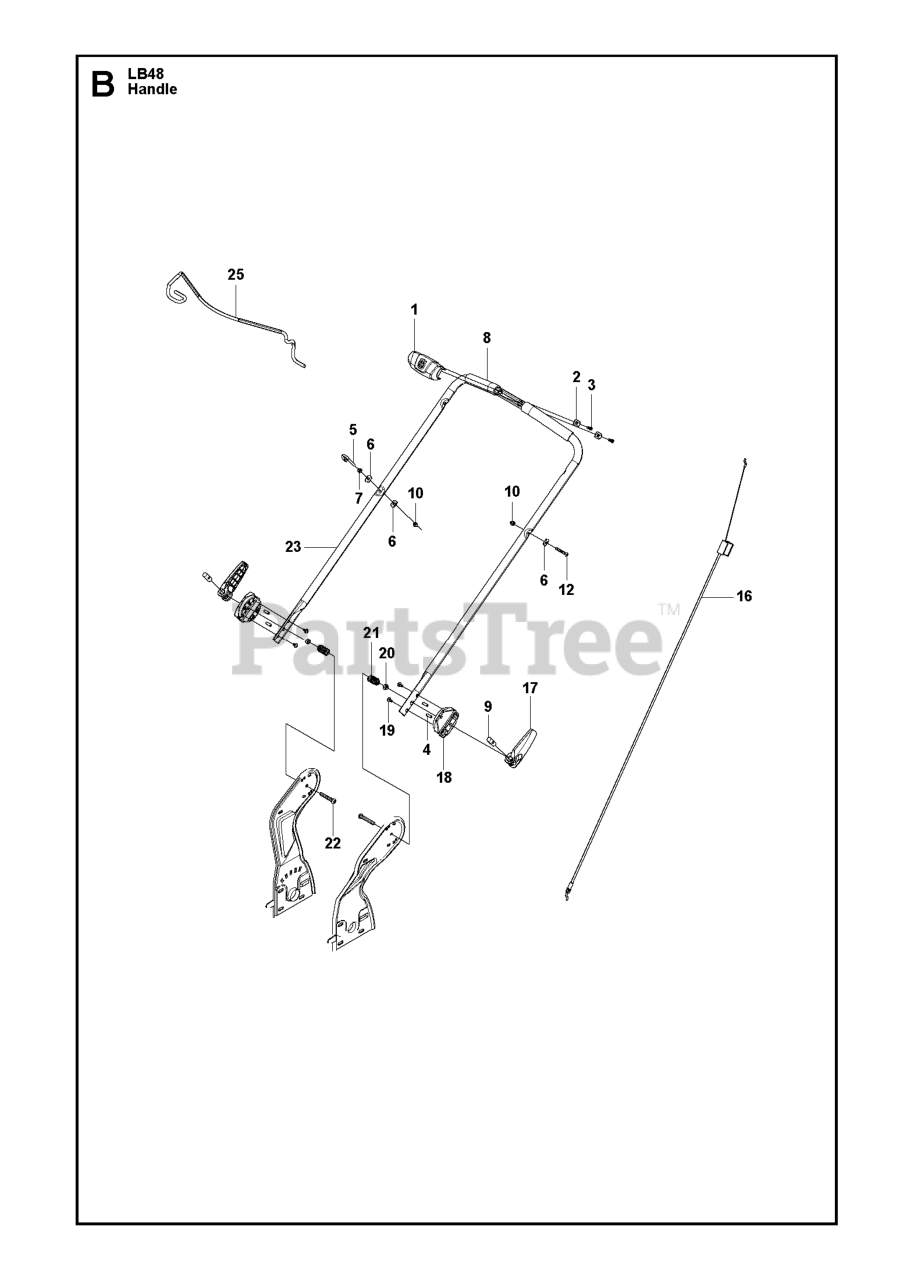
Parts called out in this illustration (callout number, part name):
3	SCREW ITXPANT T50X16 ZN/FE (A
13	COVER, DRIVE CONTROL, TOP
14	BRACKET, DRIVE CONTROL
15	SCREW ITXPANT T50X16 ZN/FE (A
19	SCREW ITXPANTT M5X10 ZPB (A00
